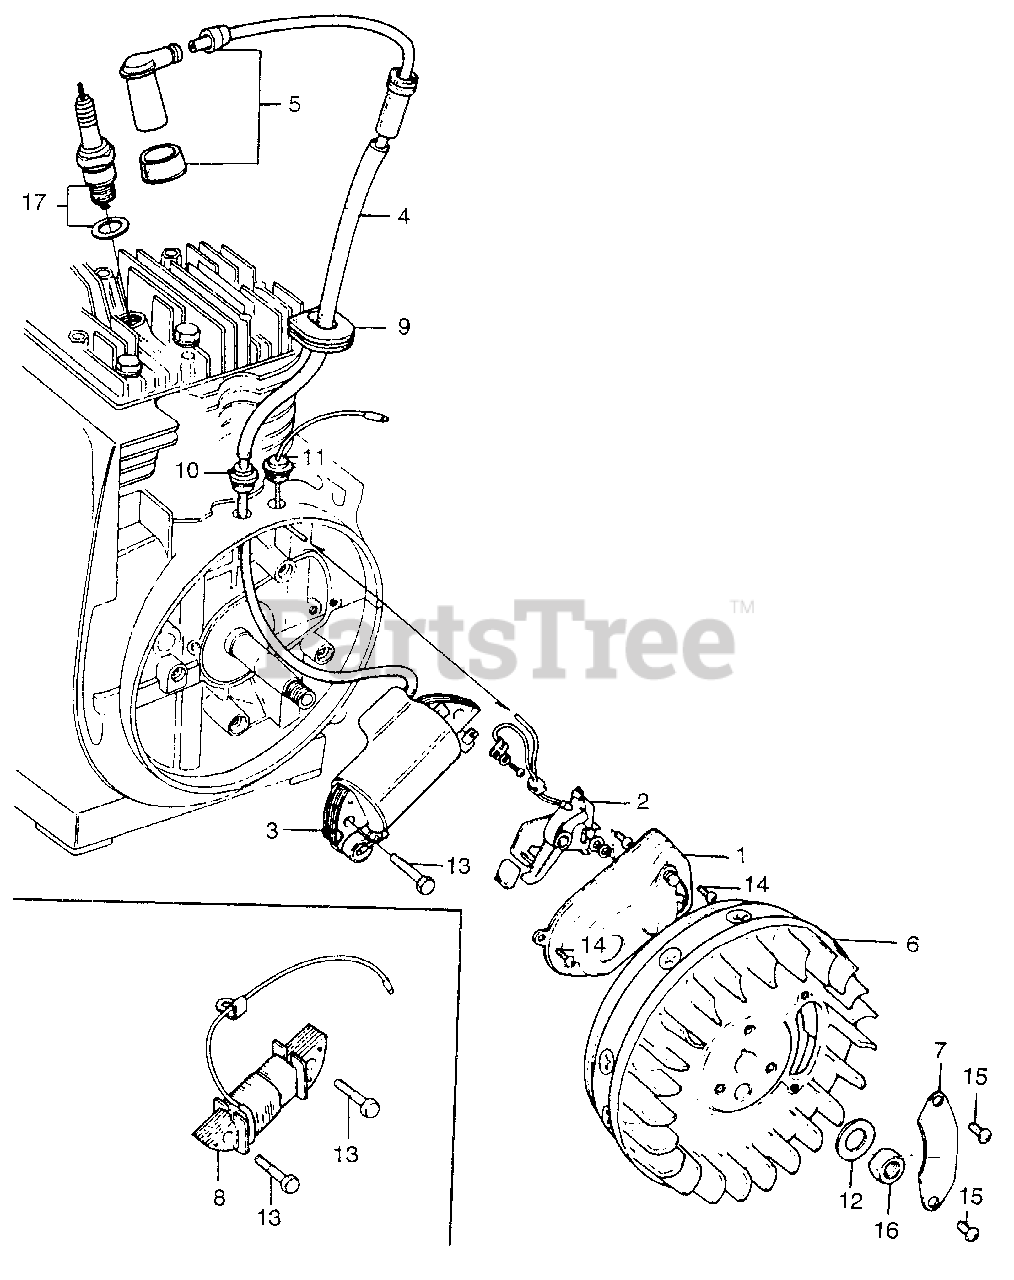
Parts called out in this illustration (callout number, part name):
1	COVER, POINTS (NOT AVAILABLE)
2	POINTS ASSY. (NOT AVAILABLE)
3	COIL, IGNITION (NOT AVAILABLE)
4	TUBE, IGNITION RUBBER
5	TERMINAL ASSY., IGNITION (NOT AVAILABLE)
7	COVER, FLYWHEEL WINDOW (NOT AVAILABLE)
8	COIL, EXCITER (NOT AVAILABLE)
9	GROMMET, CORD
10	GROMMET, WIRE (NOT AVAILABLE)
11	GROMMET, WIRE
12	WASHER (14MM) (NOT AVAILABLE)
13	BOLT, HEX. (6X28)
14	SCREW, PAN (5X10)
15	SCREW, PAN (5X10)
16	NUT, HEX. (14MM)
17	SPARK PLUG (B6HS) (NGK)
